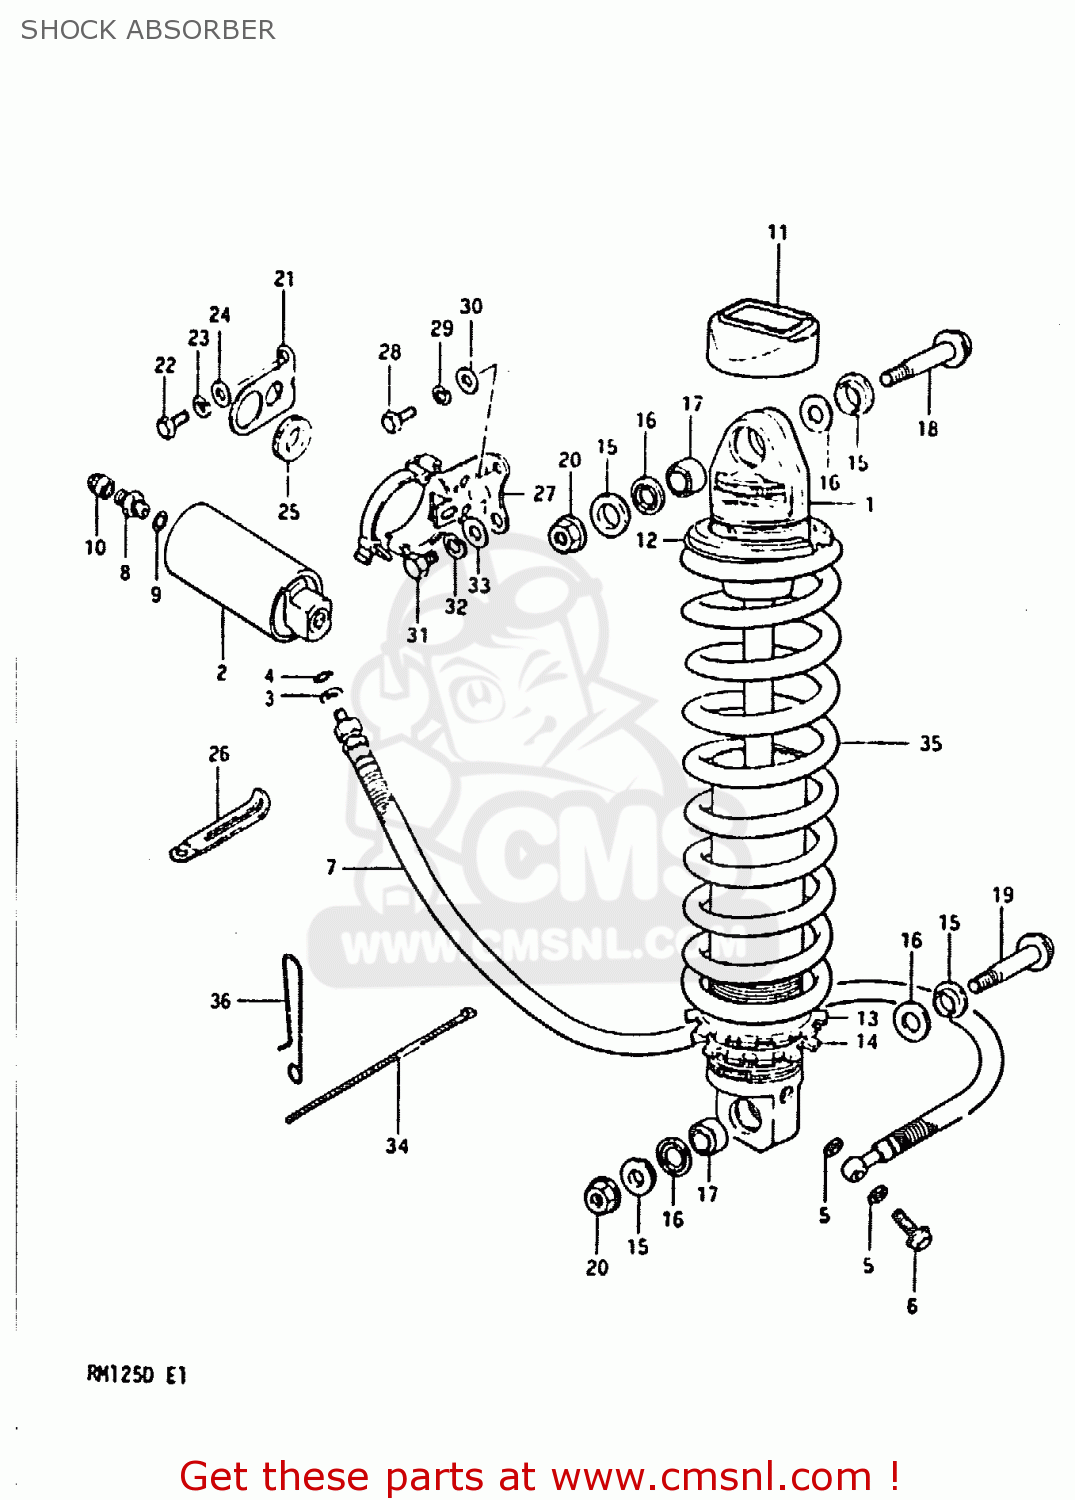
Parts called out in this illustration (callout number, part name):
1	ABSORBER ASSEMBLY,REAR SHOCK
2	RESERVE TANK,REAR SHOCK
3	WASHER,REAR SHOCK HOSE
4	O-RING,RESERVE TANK
5	GASKET (NAS)
6	BOLT,REAR SHOCK ABSORBER
7	HOSE,REAR SHOCK ABSORBER
8	VALVE,FRONT FORK AIR
9	O-RING
10	CAP
11	CLIP
12	SPRING GUIDE
13	GUIDE,SPRING
14	GUIDE,REAR SHOCK ABSORBER SPRING
15	COLLAR
16	DUST SEAL,LWR
17	BEARING
18	BOLT
19	BOLT(10X54)
20	NUT
21	BRACKET,RESERVOIR TANK
22	BOLT
23	LOCK WASHER
24	WASHER
25	CUSHION,RESERVOIR TANK
26	CLAMP
27	BRACKET,RESERVOIR TANK
28	BOLT
29	LOCK WASHER
30	WASHER
31	BOLT
32	LOCK WASHER
33	WASHER
34	CLAMP
35	SPRING
36	GUIDE RES HOSE CLAMP
